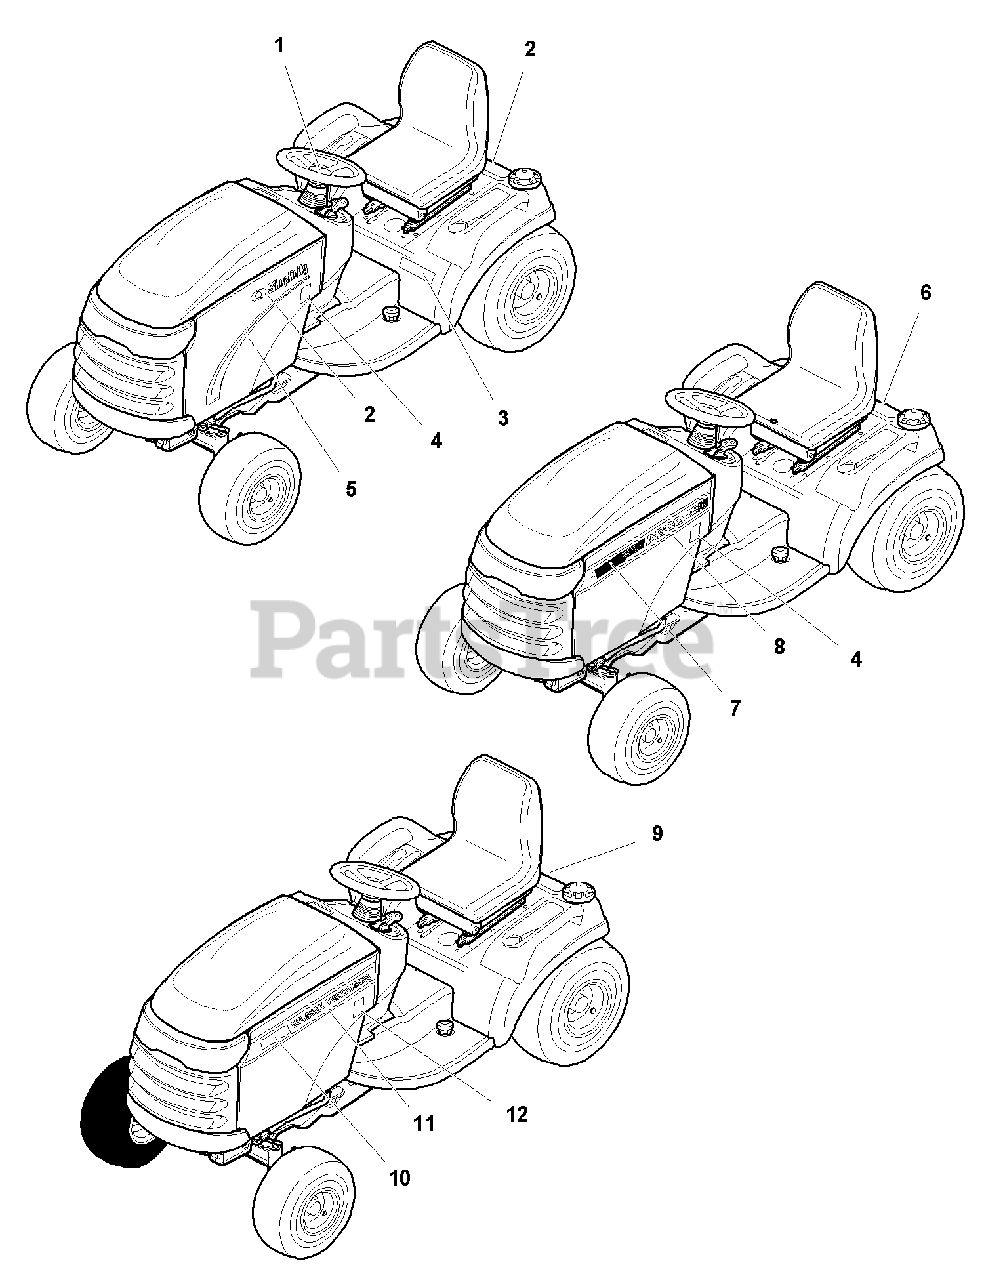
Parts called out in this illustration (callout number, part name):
1	DECAL, ICON Simplicity, Orange
2	DECAL, Simplicity, Silver & Blue w/Icon
3	DECAL, Broadmoor, Silver & Blue
4	DECAL, Touch Up Paint (Orange)
5	DECAL, Hood Stripe, RH, Simplicity, Blue & Silver
5	DECAL, Hood Stripe, LH, Simplicity, Blue & Silver
6	DECAL, AGCO, Logo Black, Chrome, Orange
7	DECAL, 1606, White, AGCO
7	DECAL, 1616, White, AGCO
8	DECAL, Hood Stripe, LH, AGCO
8	DECAL, Hood Stripe, RH, AGCO
9	DECAL, Massey Ferguson Logo, 3 Triangles
10	DECAL, 2606, Black, Massey Ferguson
10	DECAL, 2616, Black, Massey Ferguson
11	DECAL, Hood Stripe, LH, Massey Ferguson
11	DECAL, Hood Stripe, RH, Massey Ferguson
12	DECAL, Touch Up Paint (Red)
